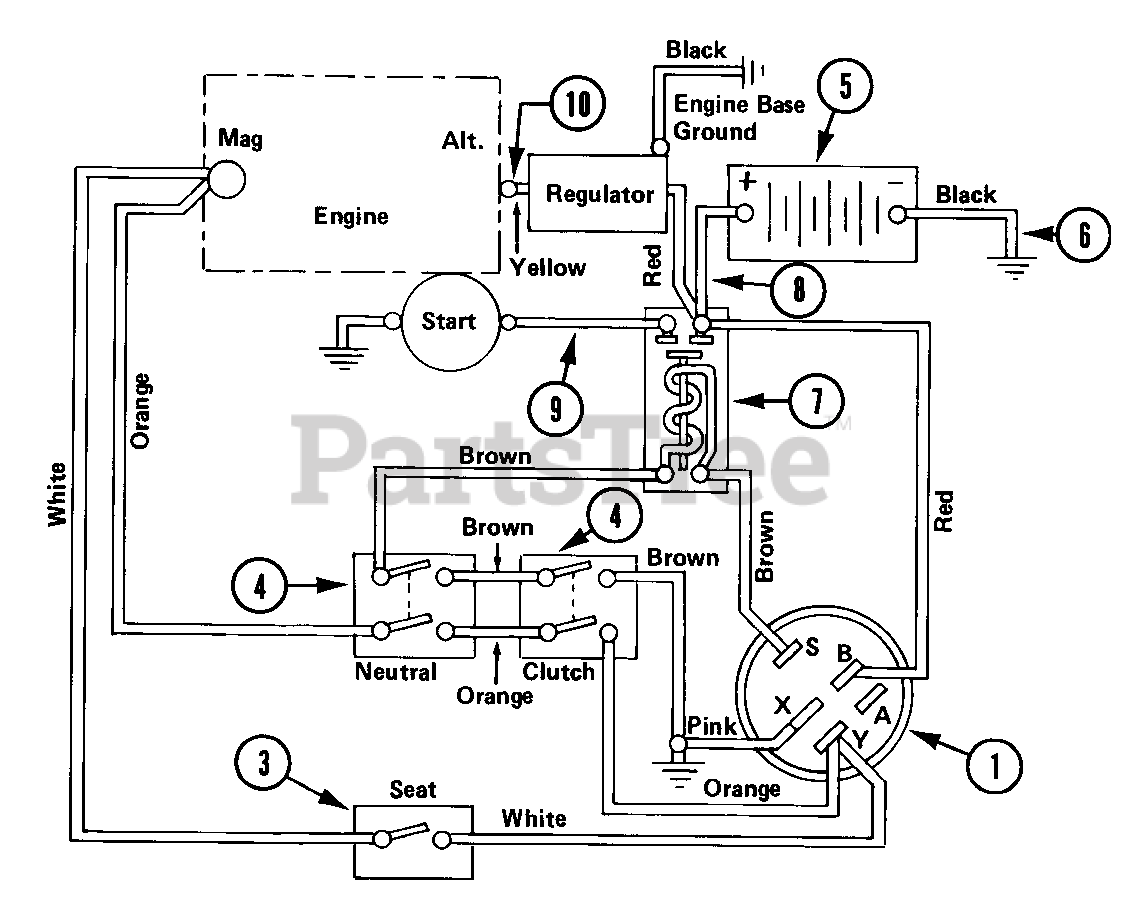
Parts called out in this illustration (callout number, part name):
1	IGNITION SWITCH ASSEMBLY
1	KEY SWITCH
3	SAFETY SWITCH
3	SEAT WITH SWITCH REPLACEMENT P
3	SWITCH SEAT
4	SWITCH INTERLOCK
4	SWITCH ASSEMBLY, N.O./N.O.
5	BATTERY
6	GROUND CABLE .25X13.00X.31
7	SOLENOID
8	STARTER CABLE 16"
9	STARTER CABLE 13"
11	ADAPTER - SEAT SWITCH
12	WIRE HARNESS GROUND TO RUN
14	REGULATOR
